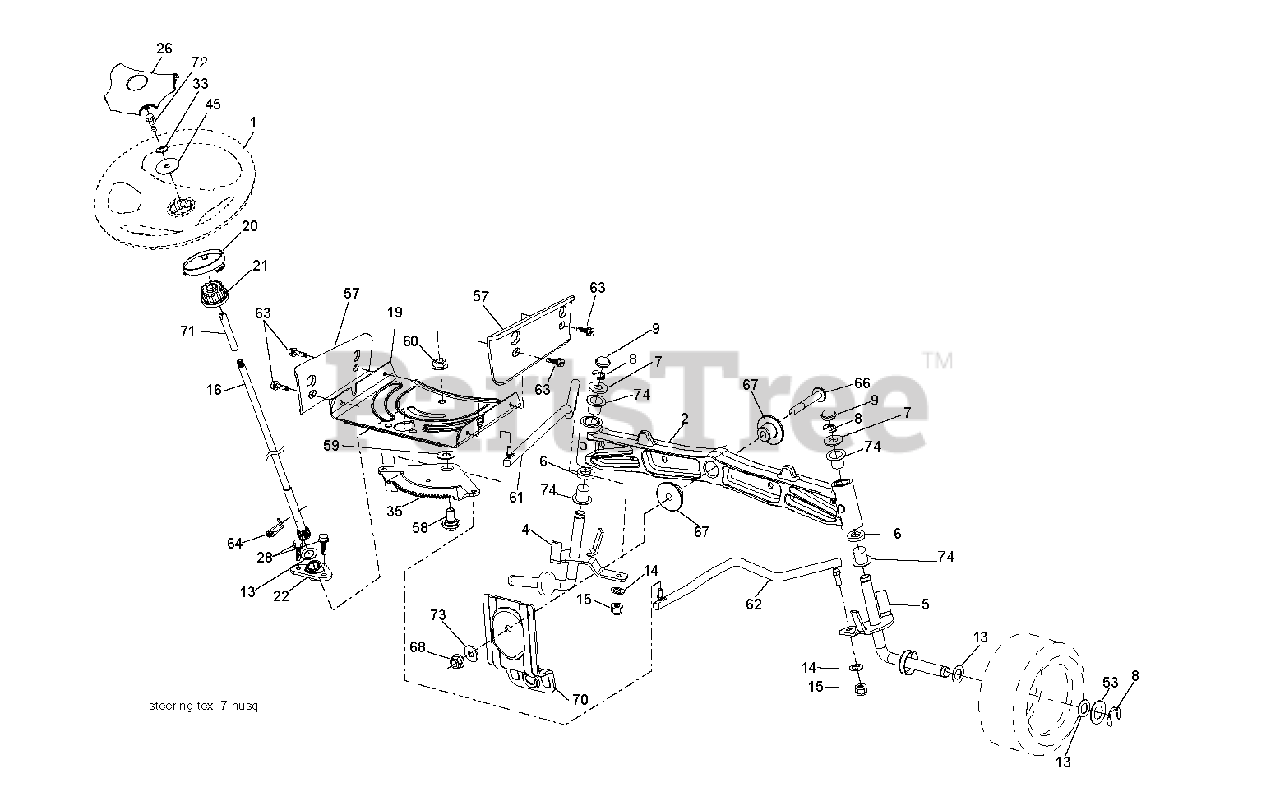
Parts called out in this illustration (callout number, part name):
1	WHEEL.STEERING.STDSRR.BLK/OV
2	AXLE HALF ASM-WELDED
4	SPINDLE.WELDED.LH.15"TEX
5	SPINDLE.WELDED.RH.15"T
8	RING CLIP
9	CAP.SPINDLE
14	WASHER, LOCK 3/8
15	NUT CROWNLOCK 3/8-24
16	SHAFT STEERING
19	PLATE.STEER.DDL.NLT/NG
20	BOOT.STEERING.PREDATOR.LT.BLAC
21	ADAPTER, WHEEL STNG..
22	BUSHING.ASM.STEERING.A
26	CAP.WHL.STRNG.STDSRRD.SRS.BLK
28	SCREW, 3/8-16X3/4
33	LOCKWASHER
35	GEAR.SECTOR.PLATE.DDL.
45	WASHER.11/32
53	WASHER.HARDENED
57	BRACKET.UPSTOP.TEX
58	BOLT.SHOULDER.SECTOR.P
59	WASHER.THURST.SECTOR.S
60	NUT FLANGE LOCK 5/8-11
61	DRAGLINK.LH.BALLSTUD.D
62	DRAGLINK.RH.BALLSTUD.D
63	SCREW
64	RETAINER.CLIP.SPRING.S
66	BOLT HEX FGHD 7/16-14 X 3 SERR
67	BUSHING.PM.FRONT AXLE
68	NUT.LOCK.FLANGE.7/16
70	BRKT.DECK.SUSPENSION.F
71	SHAFT EXTENSION STEERING
72	BOLT YT
73	WASHER.1.5X.505X.118
74	BRNG T
